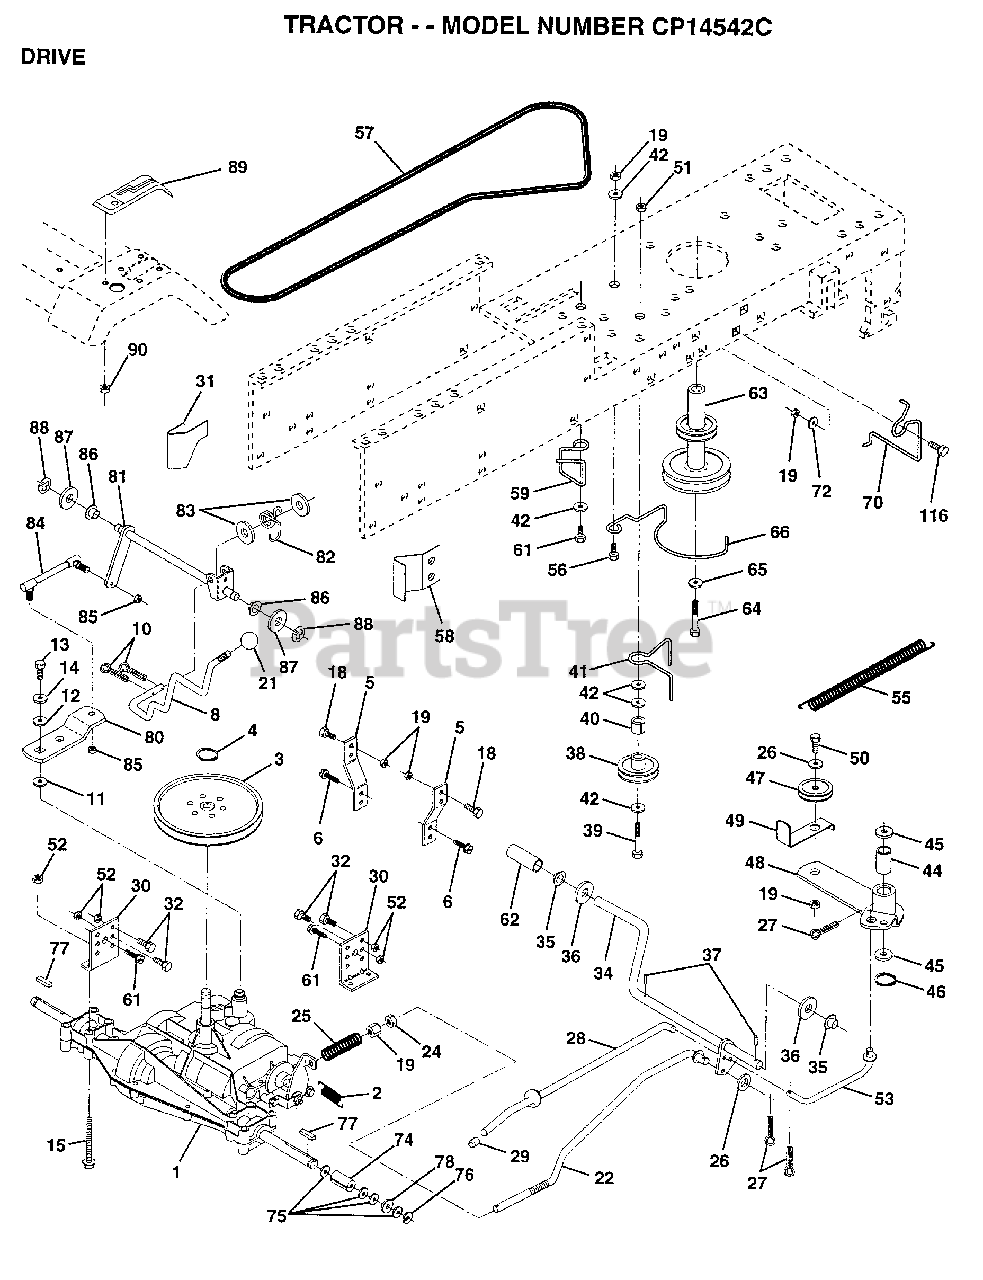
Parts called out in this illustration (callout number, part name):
2	SPRING.BRAKE.RETU
3	PULLEY TRANS
5	STRAP TORQUE
6	SCREW
8	ROD SHIFT FEND LT
10	PIN COTTER 1/8
11	WASH-SHFT PLT LT
12	WASHER
13	BOLT.1/4-28.W/PAT
14	LOCKWASHER
15	BOLT.HX.FLG.5/16
18	BOLT
19	NUT
21	KNOB T (1/2-HOLE)
22	BRAKE ROD
24	NUT
25	SPRING ROD LT
26	WASHER
27	COTTER PIN
28	ROD.BRAKE.PARK.LT
29	PLUNGER CAP T
30	TRANSAXLE MTG BKT
31	"KEEPER,BELT LH T"
32	BOLT
34	SHAFT.PEDAL.FOOT
35	NYLON BEARING
36	WASHER LT
38	PULLEY.IDLER.FLAT
39	BOLT
40	SPACER T
41	BELT KEEPER LT
42	WASHER
44	"LY, BEARING"
45	WASHER LT
46	KLIP RING
48	ARM IDLER
49	RETAIN BELT
53	"LINK, CLUTCH T"
55	"SPRING, RETURN LT"
58	"KEEPER,BELT RH T"
59	KEEPER BELT CNTSP
61	SCREW
62	PEDAL COVER T
63	PULLEY.ENGINE
64	BOLT
65	LOCKWASHER
66	KEEPER.BELT.ENG.L
70	KEEPER BELT ENG
72	WASHER
74	SPACER LT
75	WASHER
76	E-RING LT
77	SQUARE KEY
78	WASHER
80	ARM SHIFT TRANS
81	SHAFT ASM.SHIFT
82	"SPRING,TORSION"
83	WASHER
84	TIE ROD
85	NUT.CNT.LOCK.1/4
86	BUSHING
87	WASHER D
88	KLIP RING
90	NUT
